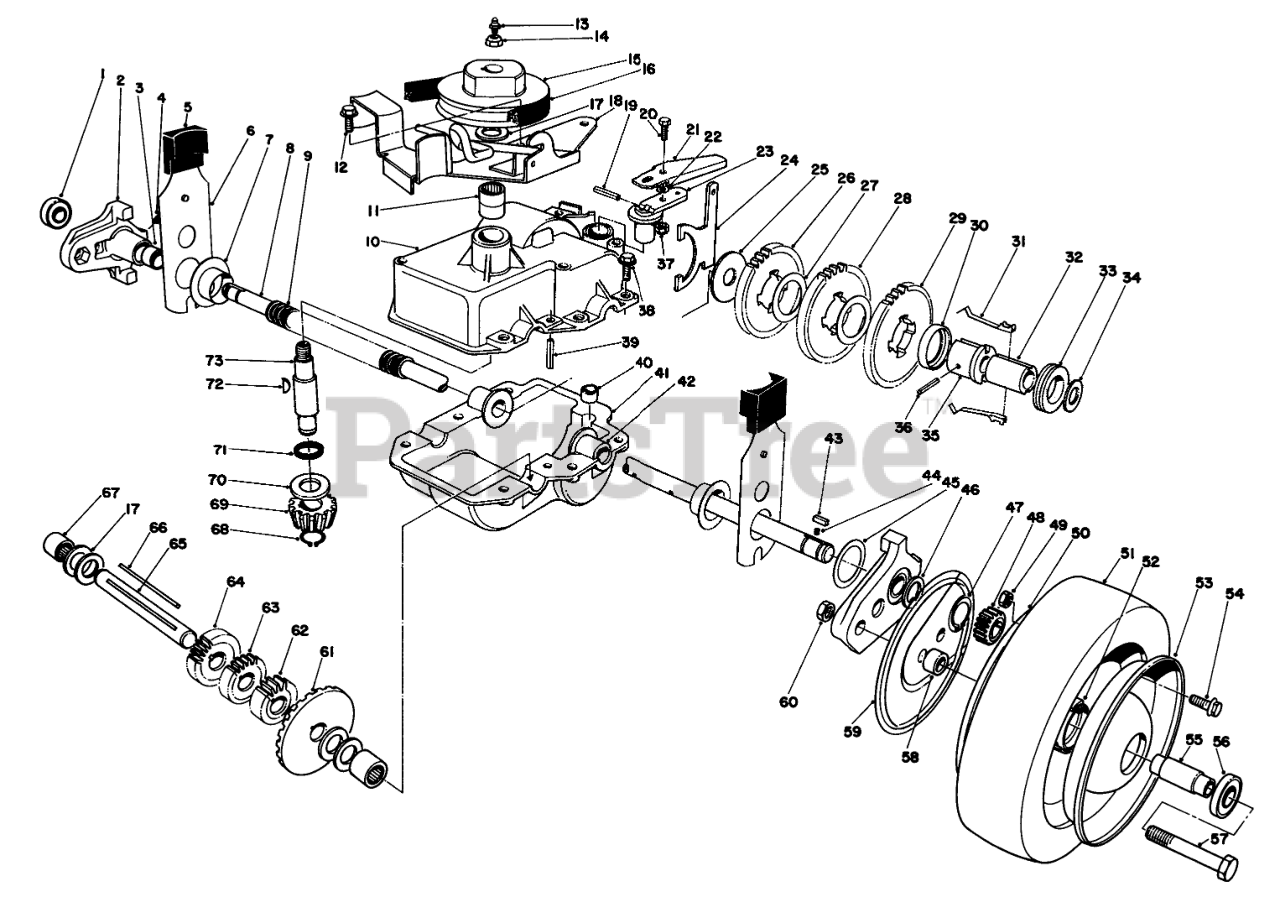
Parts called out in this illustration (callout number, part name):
1	BEARING-WHEEL
2	Pivot Arm Assembly (Incl. Ref. #1 & 3-4)
3	BUSHING
4	FITTING-GREASE
5	KNOB-ARM
6	Spring Arm
7	CAP-END
8	Output Shaft
9	CONDUIT-CONVOLUTED, SPLIT
10	Case Upper
11	BEARING-NEEDLE
12	SCREW
13	FITTING-GREASE
14	NUT-HEX
15	PULLEY
16	V-BELT
17	WASHER-THRUST
18	BELT GUIDE BRKT W A
19	PIN-COIL
21	Cover-Shift Lever
22	WASHER-FLAT
23	LEVER-SHIFT
24	Shift Yoke
25	WASHER
26	GEAR-38T
27	WASHER
28	GEAR-42T
30	KEY RETAINER
31	KEY-SHIFT
32	SLEEVE
33	COLLAR-SHIFT
34	WASHER-PLAIN
35	Body-Sleeve
36	PIN-SPIROL
37	NUT-LOCK, NI
38	SCREW-HWHTF
39	ROLL PIN 3/16 X 1 IN
40	BUSHING-YOKE
41	Case-Lower
42	BUSHING
43	KEY RECTANGULAR
44	Spring
45	WASHER
46	KEYED WASHER
47	RING-RETAINING
48	GEAR-PINION
49	NUT-LOCK, NI
50	Wheel-Inner Half
52	HUB-BEARING
53	Wheel-Half
54	SCREW-HHF
55	SPACER-BEARING
56	BEARING-WHEEL
57	SCREW-HH
58	SPACER-WHEEL
59	WHEEL COVER
60	Nut-Lock
61	BEVEL GEAR
62	GEAR-12T
63	GEAR-14T
64	GEAR-18T
65	Shaft-Intermediate
66	Key Square
67	BEARING-NEEDLE, CLOSED
68	RING-RETAINING
69	PINION-BEVEL
70	WASHER-THRUST
72	KEY-WOODRUFF
73	Shaft Input
